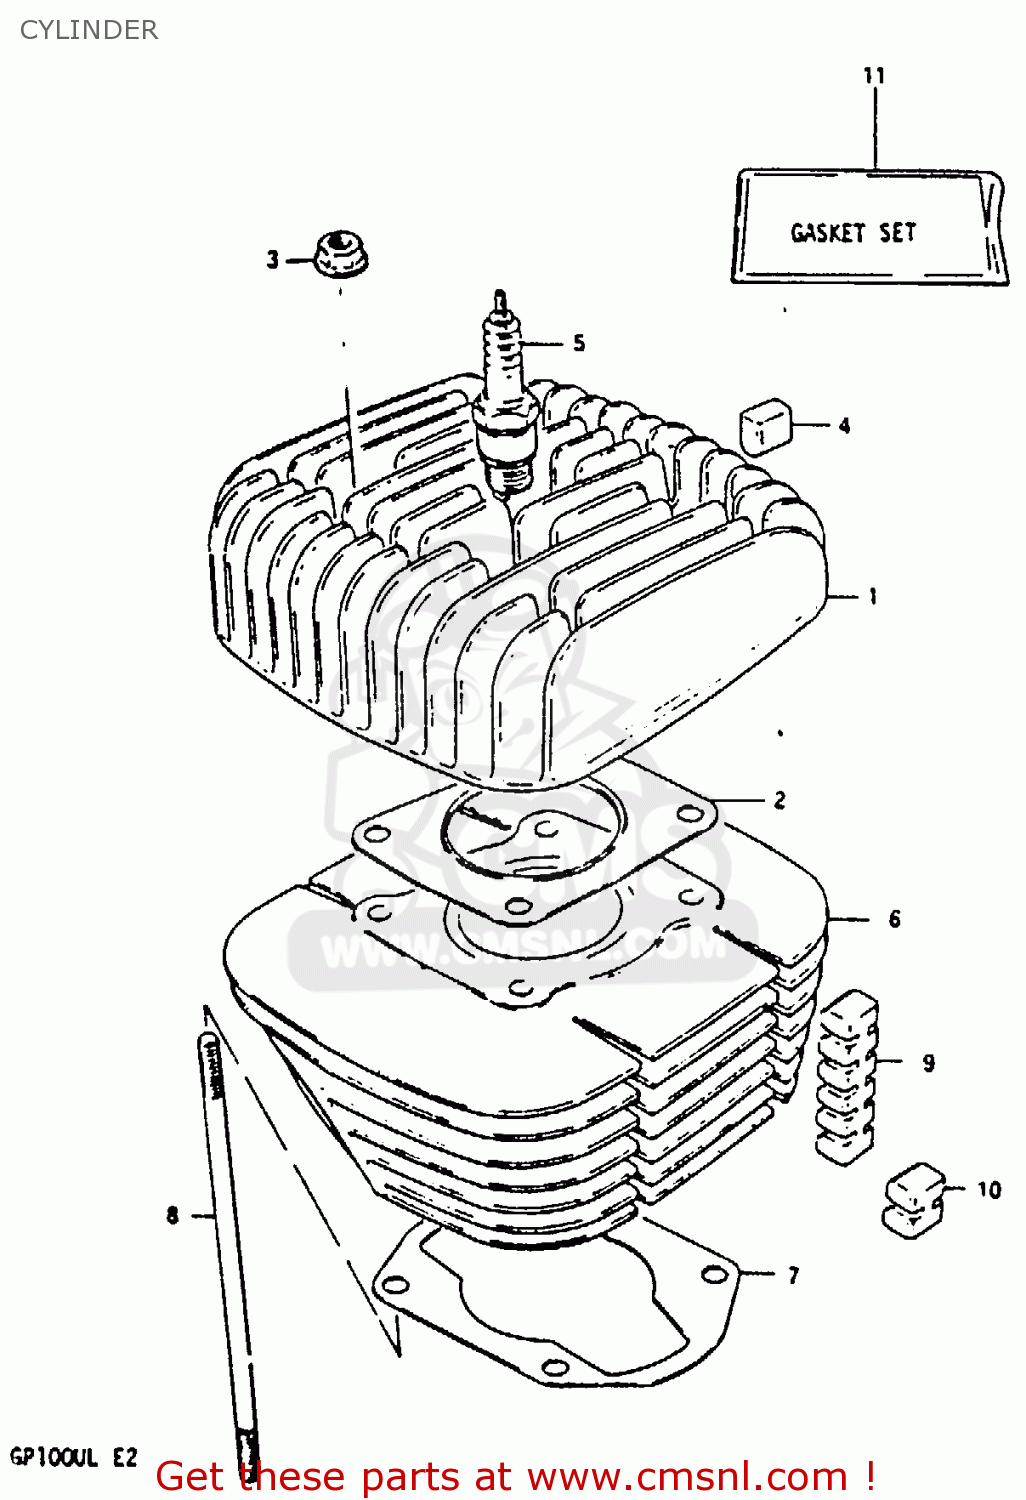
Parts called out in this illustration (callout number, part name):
1	HEAD,CYLINDER
2	GASKET, CYLINDER HEAD (MCA)
3	NUT
4	PAD,CYLINDER
5	PLUG,SPARK(B8HS)
6	CYLINDER
7	GASKET, CYLINDER (MCA)
8	BOLT,STUD
9	PAD,CYLINDER
10	PAD,CYLINDER
11	GASKET SET (MCA)
